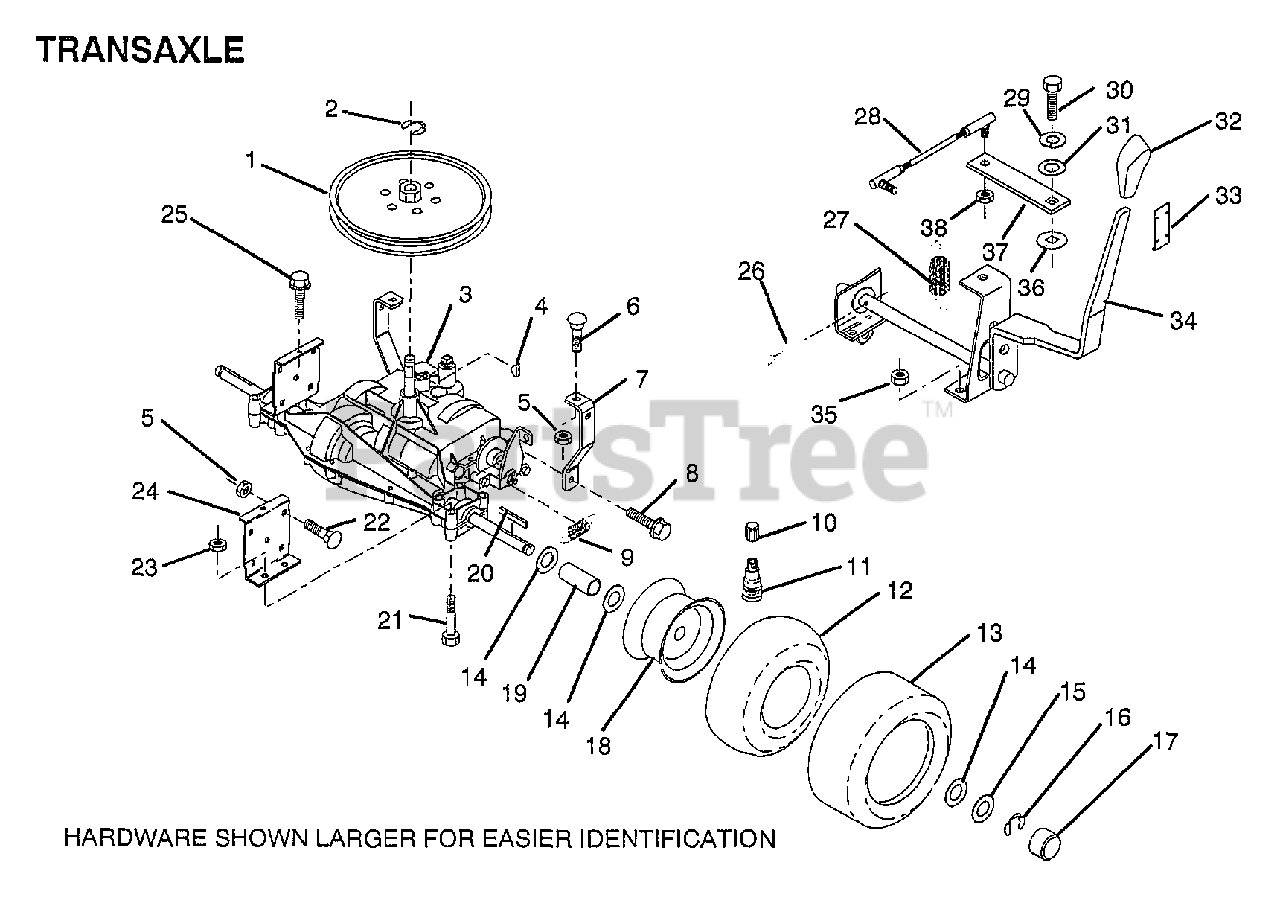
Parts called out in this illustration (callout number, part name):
1	PULLEY
6	BOLT
7	"STRAP,TORQUE"
8	SCREW LT
10	VALVE CAP
11	VALVE STEM LT
12	TUBE.16X6.5/7.5-8
13	TIRE.16X7.5-8
14	WASHER
15	WASHER
16	E-RING LT
17	HUB CAP
19	SPACER
20	SQUARE KEY
21	BOLT
22	BOLT
24	"BRKT,TRANSAXLE"
25	SCREW
26	PIN COTTER 1/8
27	EXT SPRING
28	"LINK,SHIFT"
29	LOCKWASHER
31	WASHER LT
32	"KNOB,SHT CONTROL"
33	KNOB RETAINER
34	SHIFT HANDLE ASSY
36	WASH-SHFT PLT LT
37	"ARM,SHIFT"
38	NUT.LOCK.5/16-24
